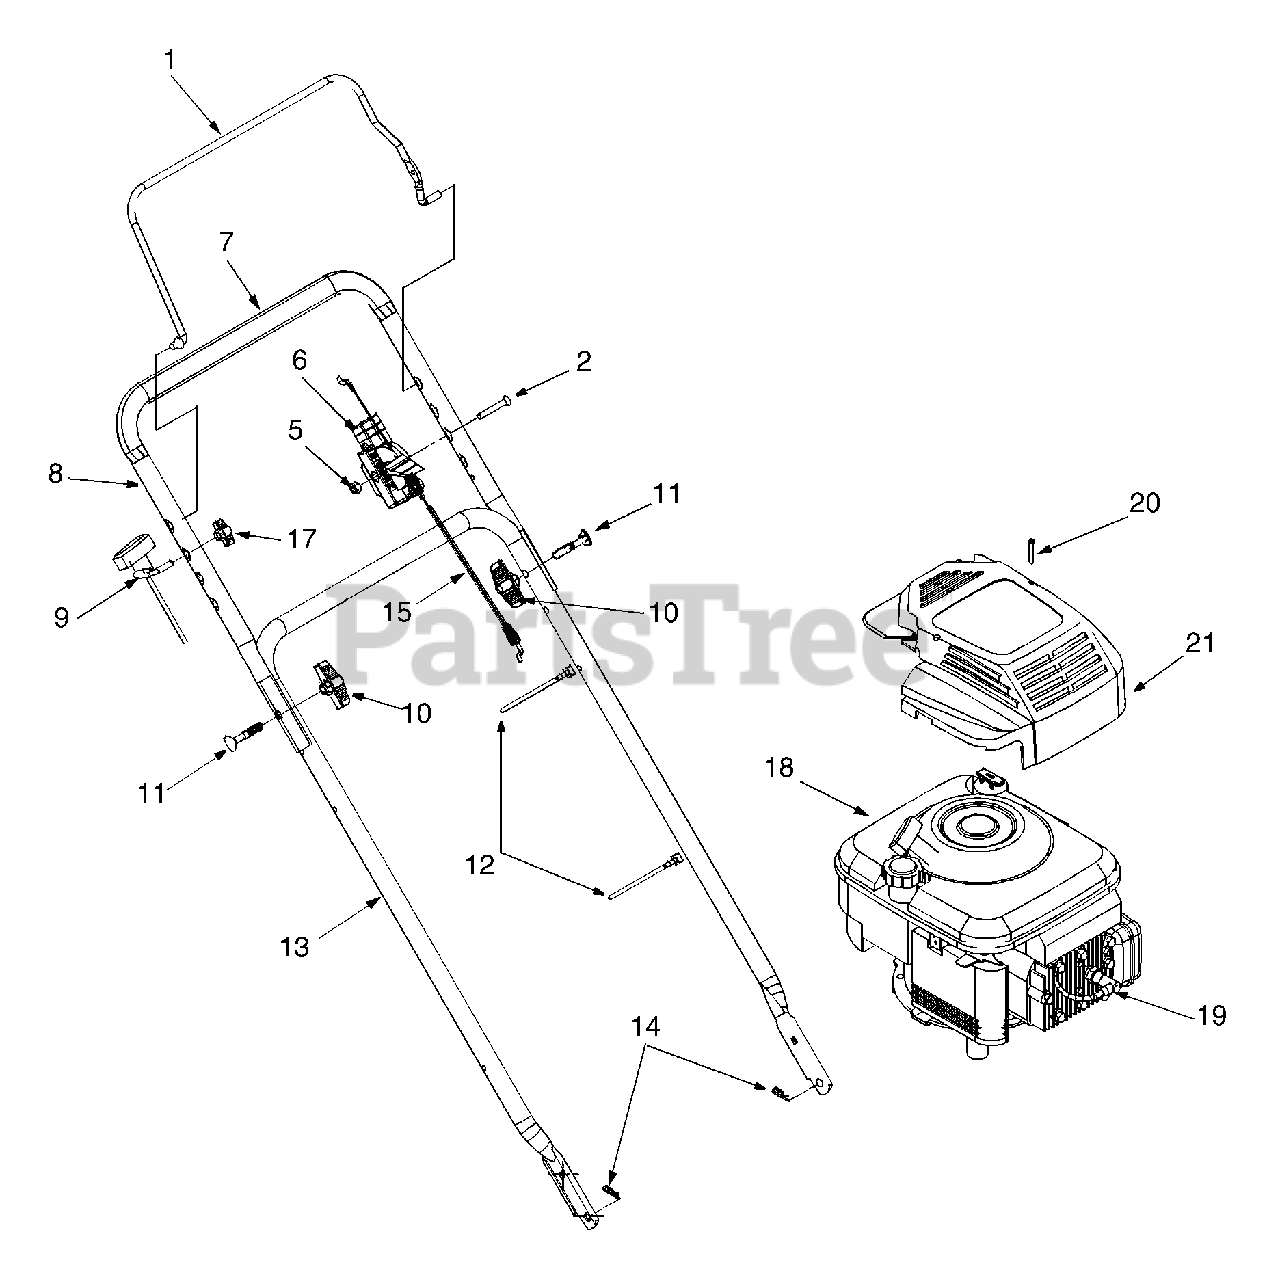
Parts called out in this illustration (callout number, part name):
1	Control Handle Ass'y.
2	Oval C-Sunk Screw
5	Hex Lock Nut
6	Control Housing
11	Carriage Bolt
12	Cable Tie
14	Hairpin Clip
15	Control Cable 39" Lg.
18	Engine
19	Spark Plug Boot
20	Hi-Lo Screw
21	Engine Shroud
